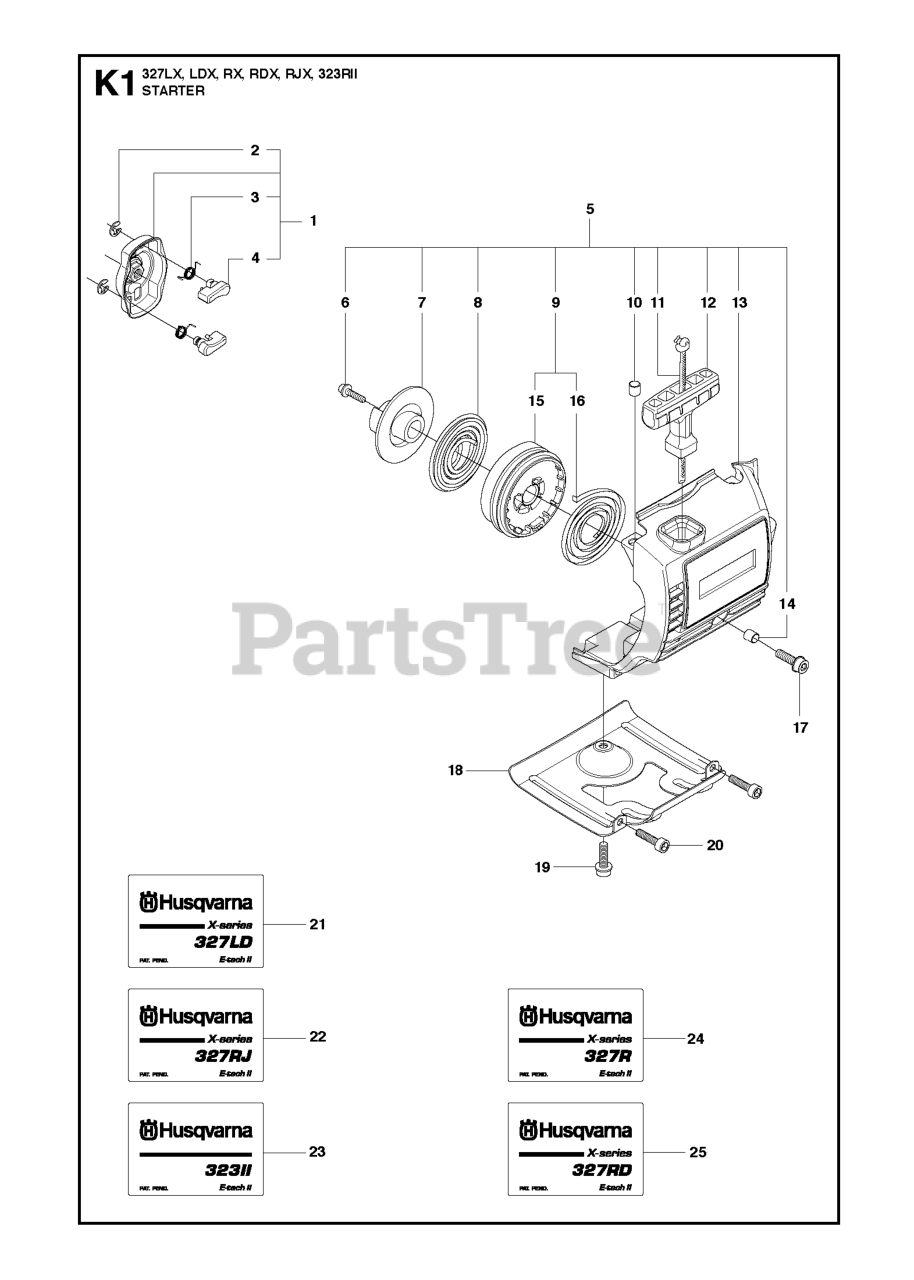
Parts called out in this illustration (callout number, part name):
1	STARTER PAWL BRIDGE
4	STARTER PAWL
5	RP STARTER ASSY
7	DRIVER PULLEY
8	SPRING - DRIVER
9	STARTER PULLEY
10	SPACING SLEEVE
11	STARTER ROPE
12	STARTER HANDLE
13	RP STARTER HOUSING
14	SPACING SLEEVE
15	STARTER PULLEY
17	SCREW
19	SCREW
21	LABEL 327LDX
22	LABEL 327RJ
23	LABEL 323 RII
24	LABEL 327RX
25	LABEL 327RDX
